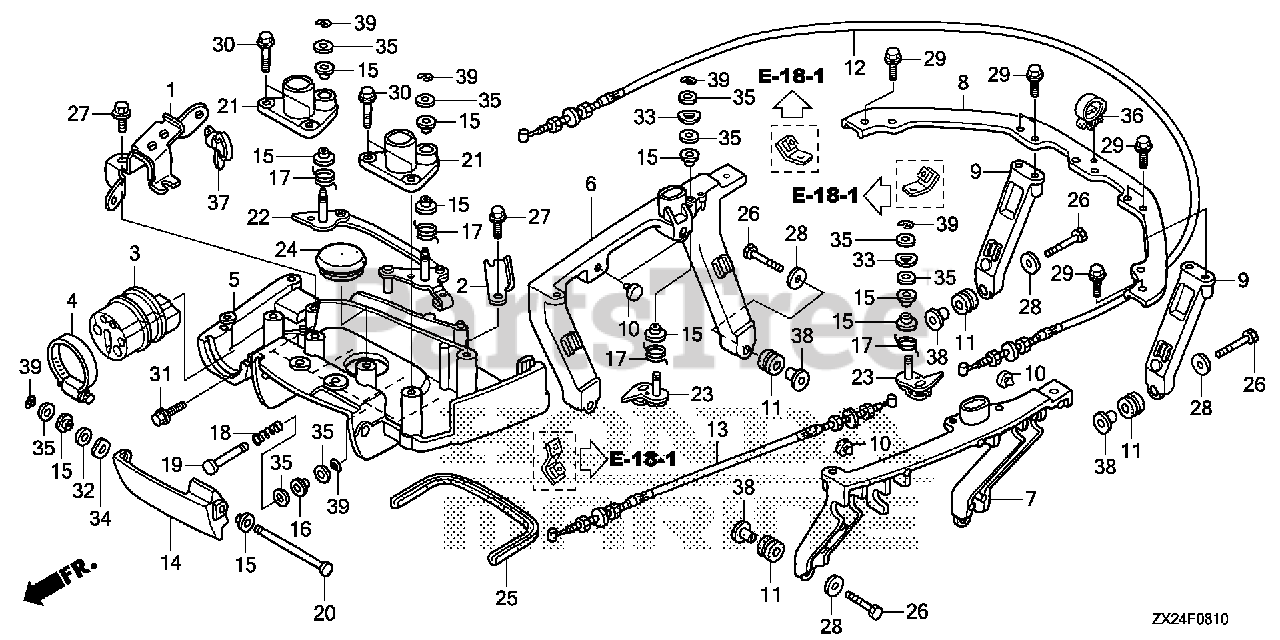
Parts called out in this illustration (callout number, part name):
1	BRACKET, CABLE
2	PLATE, STARTER CABLE
3	GROMMET A, CASE (LOWER)
4	BAND, CASE GROMMET (LOWER)
5	BRACKET, FR. COVER *NH8* (DARK GRAY)
6	BRACKET, R. SIDE COVER
7	BRACKET, L. SIDE COVER
8	BRACKET A, RR. COVER
9	BRACKET B, RR. COVER
10	RUBBER, STOPPER
11	RUBBER, FR. CARRIER CUSHION
12	CABLE A, COVER LOCK
13	CABLE B, COVER LOCK
14	LEVER, COVER LOCK *NHB14M* (AQUA MARINE SILVER METALLIC)
14	LEVER, COVER LOCK *NH565* (GRAND PRIX WHITE)
15	BUSH A, COVER LOCK
16	BUSH B, COVER LOCK
17	SPRING, COVER LOCK HOOK
18	SPRING, LOCK LEVER RETURN
19	SHAFT, COVER OPEN
20	SHAFT, FR. LOCK
21	HOLDER, STRIKER
22	LOCK ASSY., FR.
23	LOCK, SIDE
24	CAP, L. SIDE COVER
25	SEAL D, COVER (LOWER)
26	BOLT, HEX. (8X35)
27	BOLT, FLANGE (6X14)
28	WASHER, PLAIN (8MM)
29	BOLT, FLANGE (6X12)
30	BOLT, FLANGE (6X20)
31	BOLT, FLANGE (8X22)
32	WASHER, PLAIN (10MM)
33	WASHER, WAVE (8MM)
34	WASHER, WAVE (10MM)
35	WASHER, PLAIN (8MM)
36	CLIP, HARNESS
37	CLIP, HARNESS BAND (145MM) (BLACK)
38	COLLAR (8.5X14.5)
39	E-RING (6MM)
